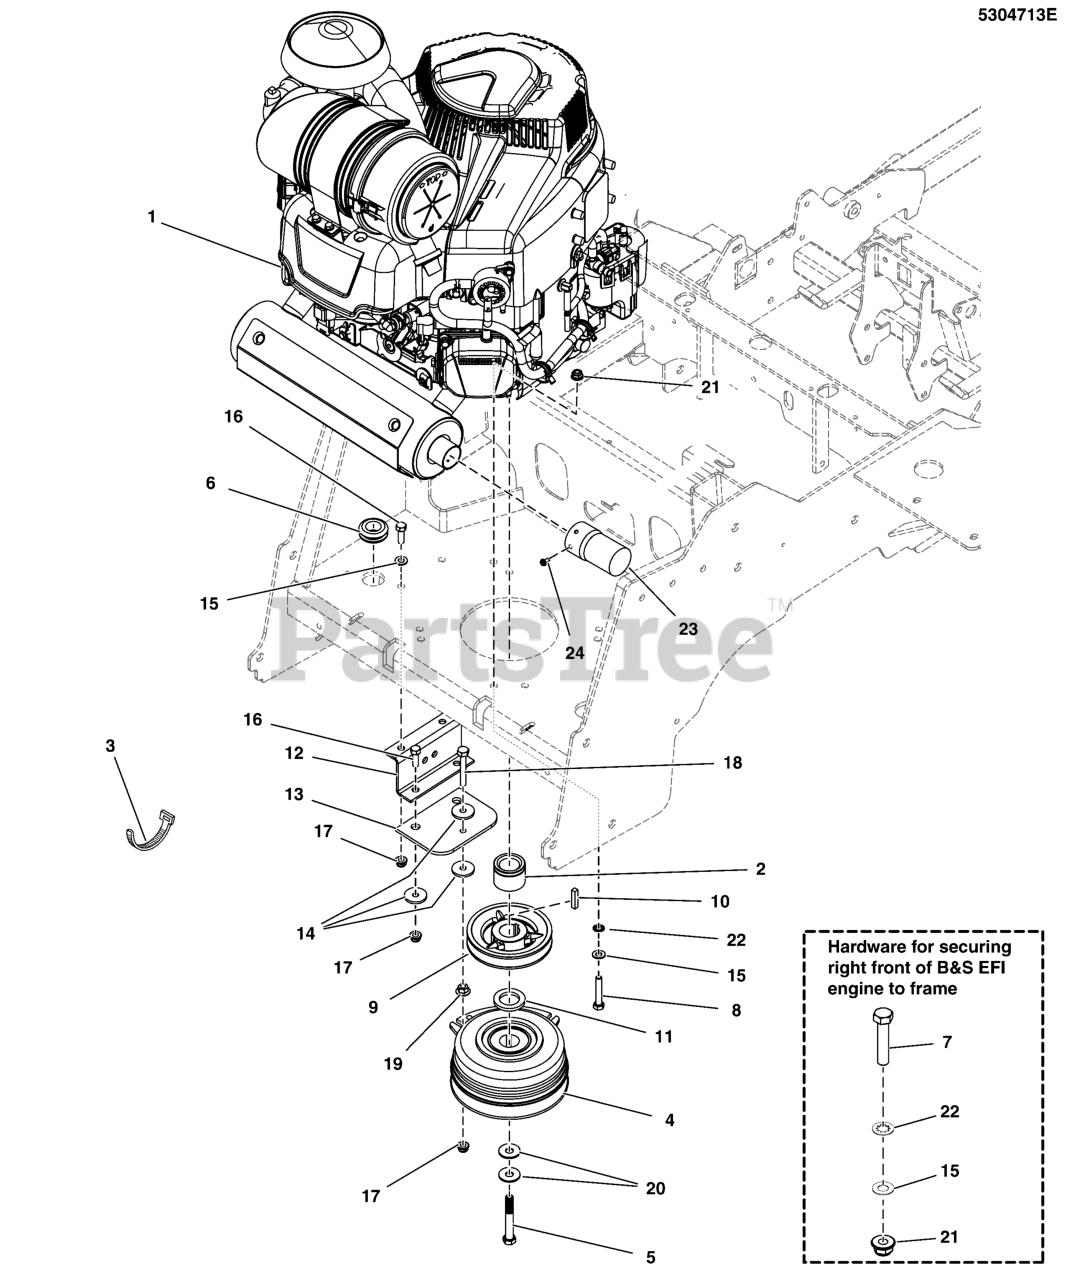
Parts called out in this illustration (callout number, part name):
1	ENGINE, 28HP EFI, B&S, W/MUF, OIL GUARD
2	SPACER, 1.13 X 1.75 X 1.35, CZ
3	TIE,SELF-LOCKING, 24"
4	CLUTCH, WARNER, 200 FT-LB, 1.13" X 6.323
5	BOLT, CRANKSHAFT, 7/16-20 X 3, GD8
6	GROMMET, 7/8"ID, 1/4" THICK STK
7	BOLT-HEX, 5/16-24 X 1-1/2", GD8, PHOS
8	BOLT, 5/16-24 X 1-3/4, GD8, PHOS
9	PULLEY, 4.75 OD X 1-1/8 BORE, BC-48
10	KEY, 1/4 SQ. X 1-1/4
11	SPACER, 1.13 X 1.75 X .25
12	ANCHOR, CLUTCH, IS600-IS700 - BLK
13	PAD, Clutch Anchor
14	WASHER, CLUTCH ANCHOR, 5/16
15	WASHER, 5/16, Flat SAE, Zinc/Clear
16	CAPSCREW, Hex Head, 5/16-18 x 1
17	NUT, Flange Nylock, 5/16-18
18	BOLT, 5/16-18 X 2-1/4
19	NUT, 5/16-18 HEX SERRATED FLANGE (LARGE)
20	BELLEVILLE, WASHER, 1.1875 X .442 X .089
21	NUT, 5/16-24, TOP LOCK FLANGE, GD8 PHOS
22	WASHER, 5/16" Internal Tooth Lock
23	EXTENSION, TAILPIPE, 3", BLACK
24	SCREW,SELF-TAP,#8-32 X 3/8, WASH HEX, CZ
